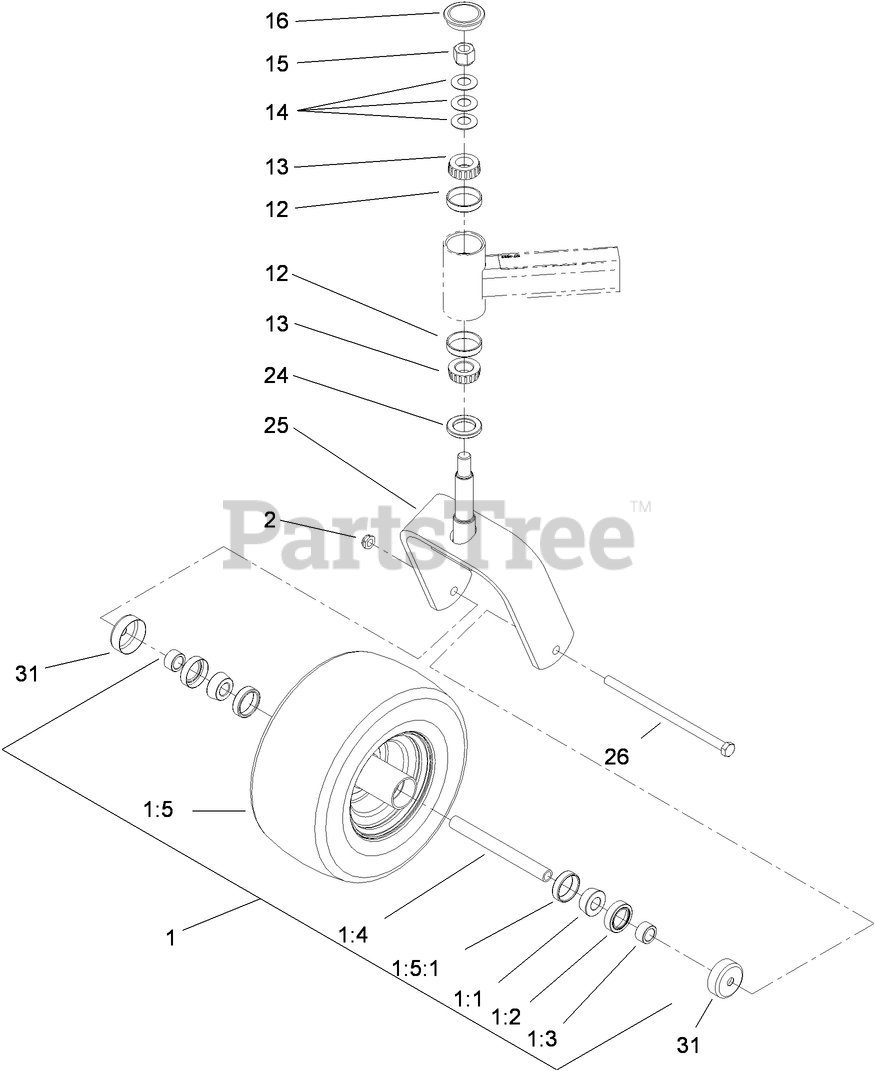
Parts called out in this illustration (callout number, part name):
1	WHEEL AND TIRE ASM
1:1	BEARING-CONE, TAPER
1:2	SEAL-CASTER
1:3	SPACER-NUT
1:4	AXLE-CASTER
1:5	WHEEL AND TIRE ASM
1:5:1	BEARING-CUP
2	NUT-LOCK, NI
12	BEARING-CUP, TAPERED
13	BEARING-CONE, TAPERED
14	WASHER-BELLVILLE
15	NUT-LOCK, NI
16	CAP-GREASE
24	SEAL-GREASE
25	CASTER-FORK
26	Screw-HH
31	GUARD-SEAL
